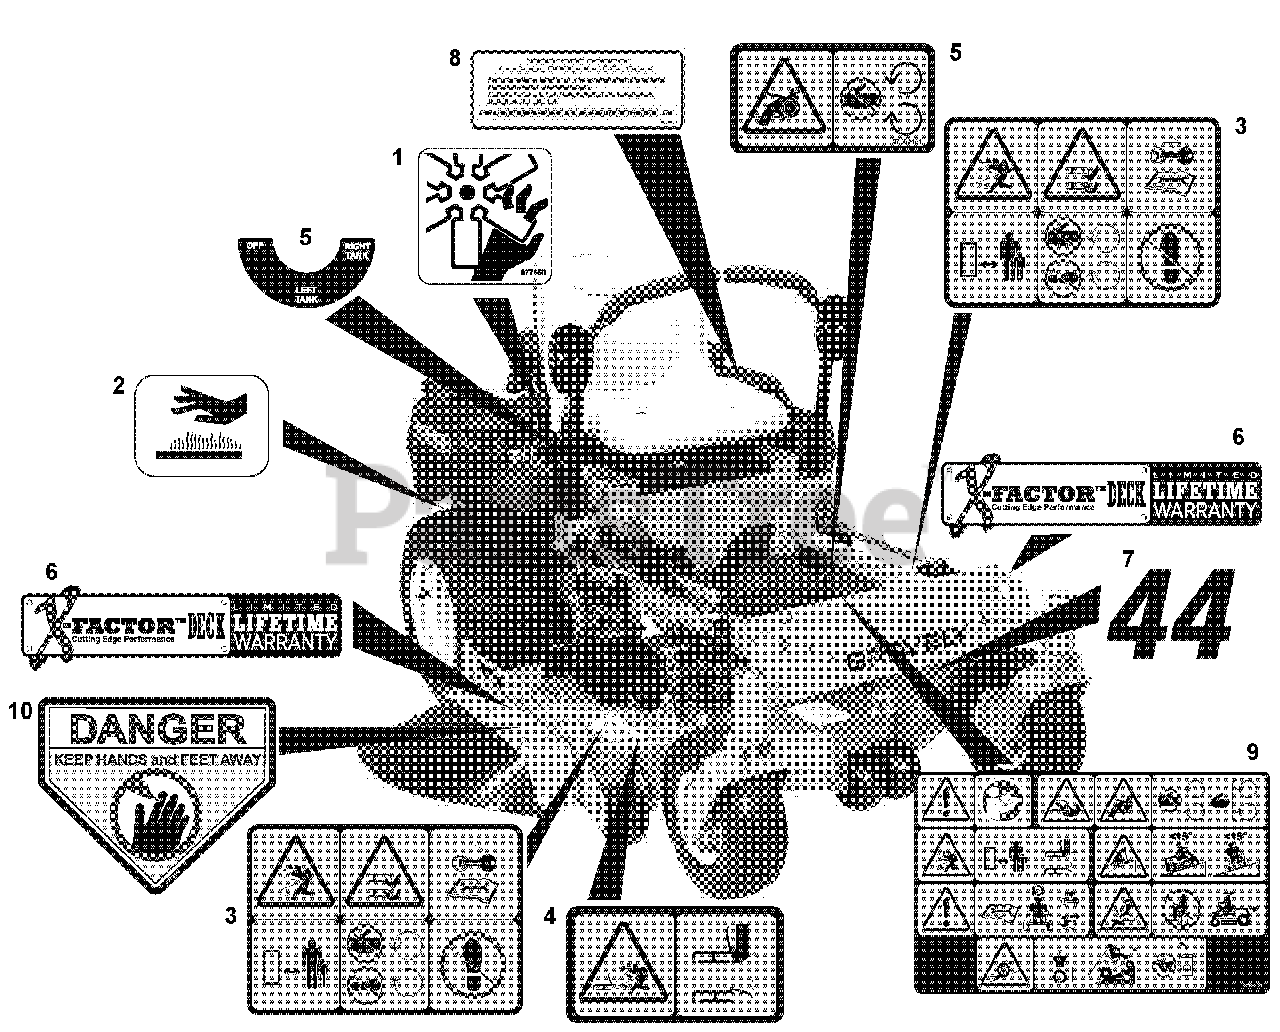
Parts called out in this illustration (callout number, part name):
1	Decal, Danger Fan
2	Decal, Hot Surface
3	Decal, Safety Mower Deck
4	Decal, Safety Deck Guarding
5	Decal, Safety Guarding
6	Decal, X-Factor Deck
7	Decal, 44
8	Decal, EPA Fuel
9	Decal, Main Safety Commercial
10	Decal, Danger
